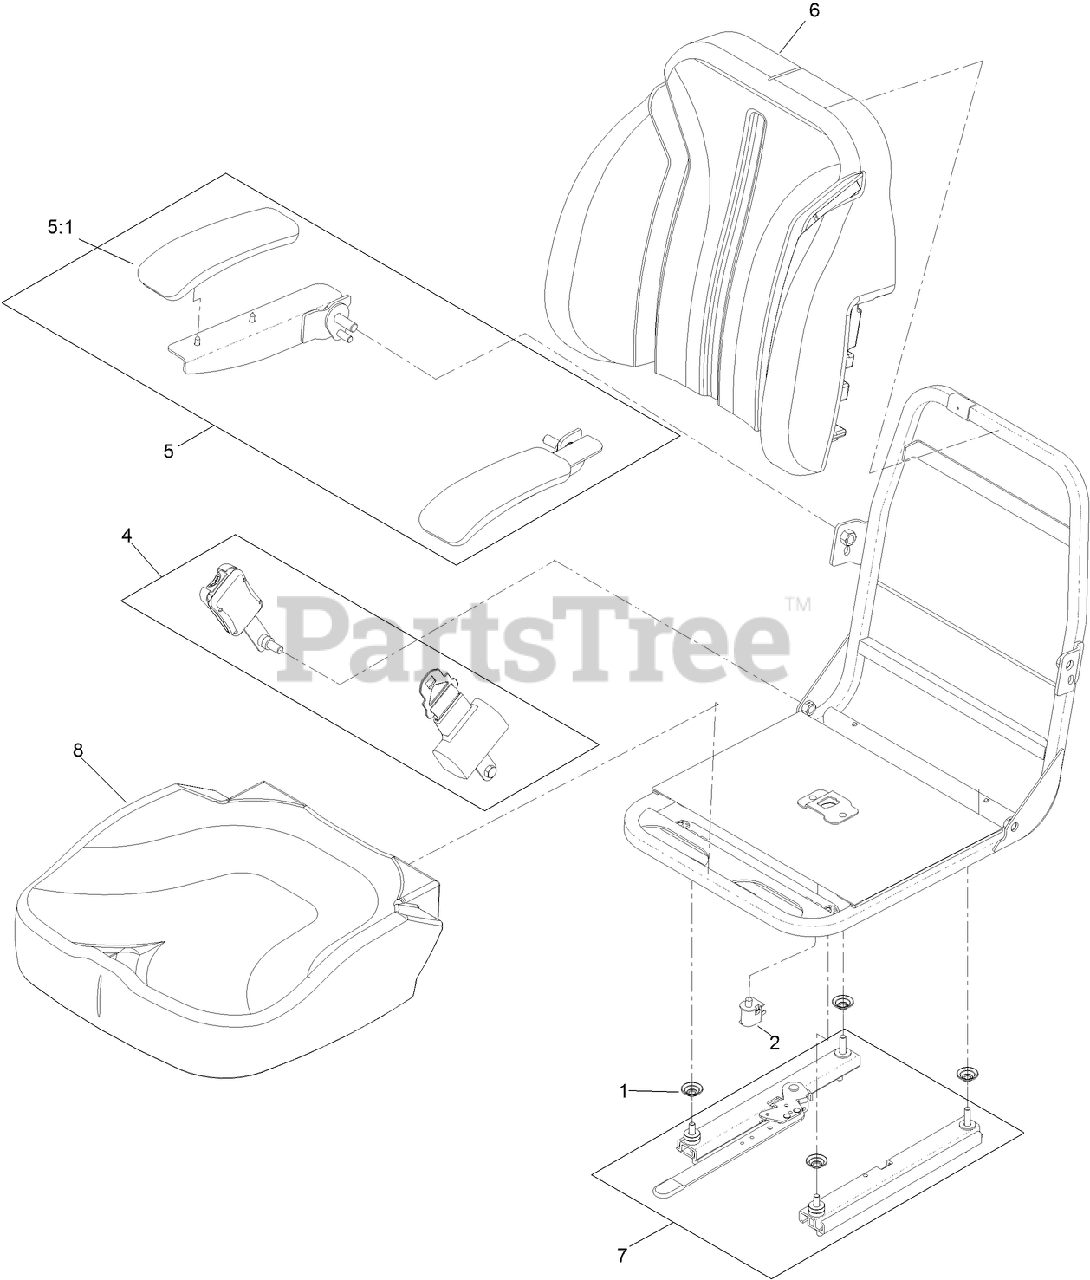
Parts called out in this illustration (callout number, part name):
1	SPACER-MOUNTING
2	SWITCH-BAIL
4	SEAT BELT KIT
5	ARMREST KIT
5:1	CUSHION-REST, ARM
6	COVER-BACK, SEAT
7	TRACK-SEAT
8	COVER-SEAT, BOTTOM
